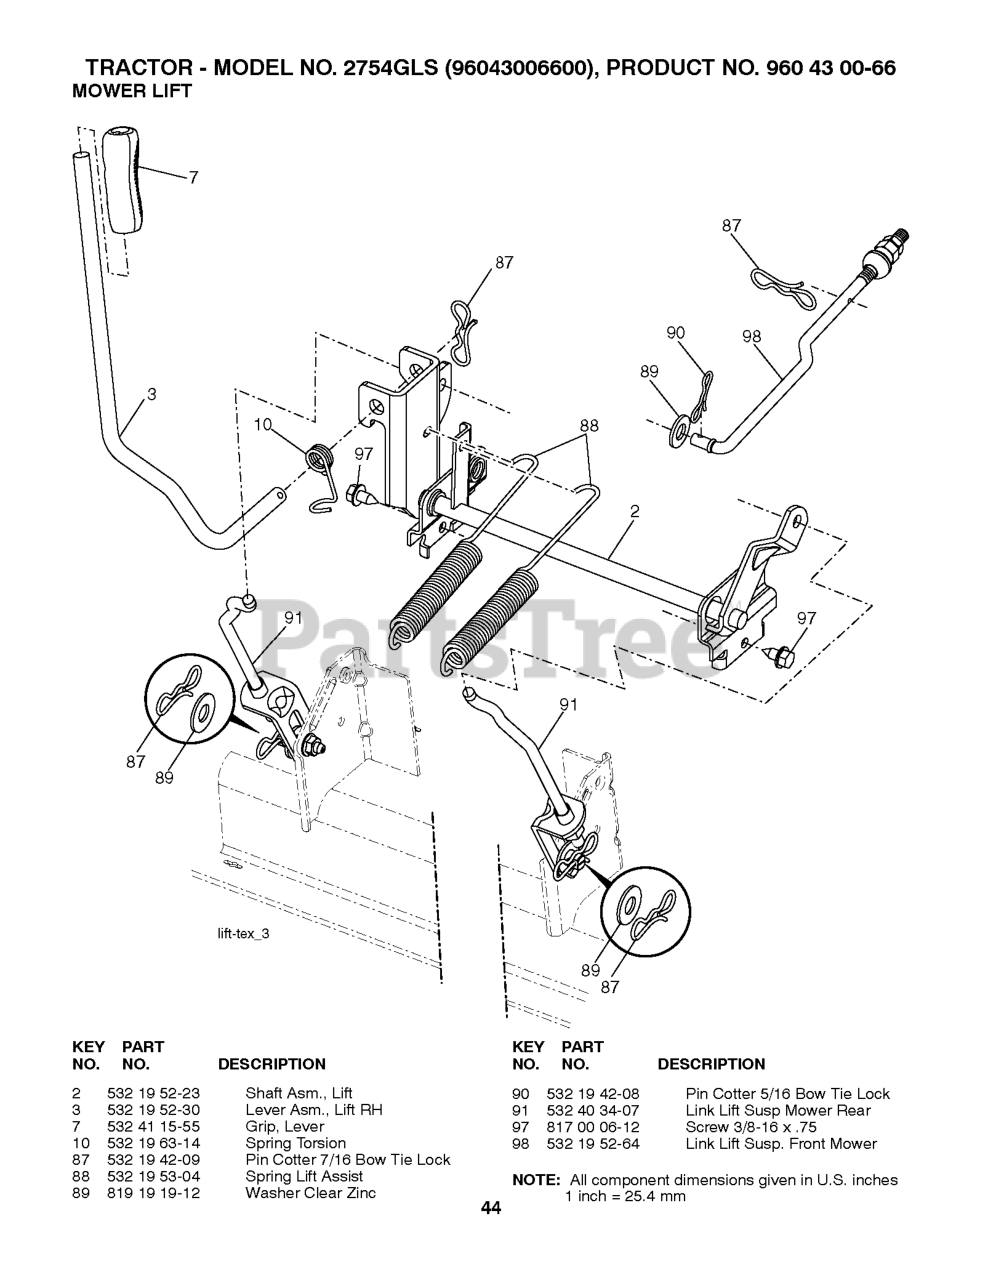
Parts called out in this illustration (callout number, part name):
2	SHAFT.ASM.LIFT.CROSS.H
3	LEVER.LIFT.HANDLE.GT
7	GRIP.HANDLE.LIFT.PVC.BLACK
10	SPRING.TORSION.LIFT.HANDLE
87	PIN.COTTER.7/16.BOW TI.
88	SPRING.LIFT.ASSIST.GT2
89	WASHER.CLEAR.ZINC
90	PIN.COTTER.5/16.BOW TI
91	LINK.ASM.LIFT.54"TG
97	SCREW, 3/8-16X3/4
98	LINK.ASM.SUSP.FRONT.MWR.10.5
